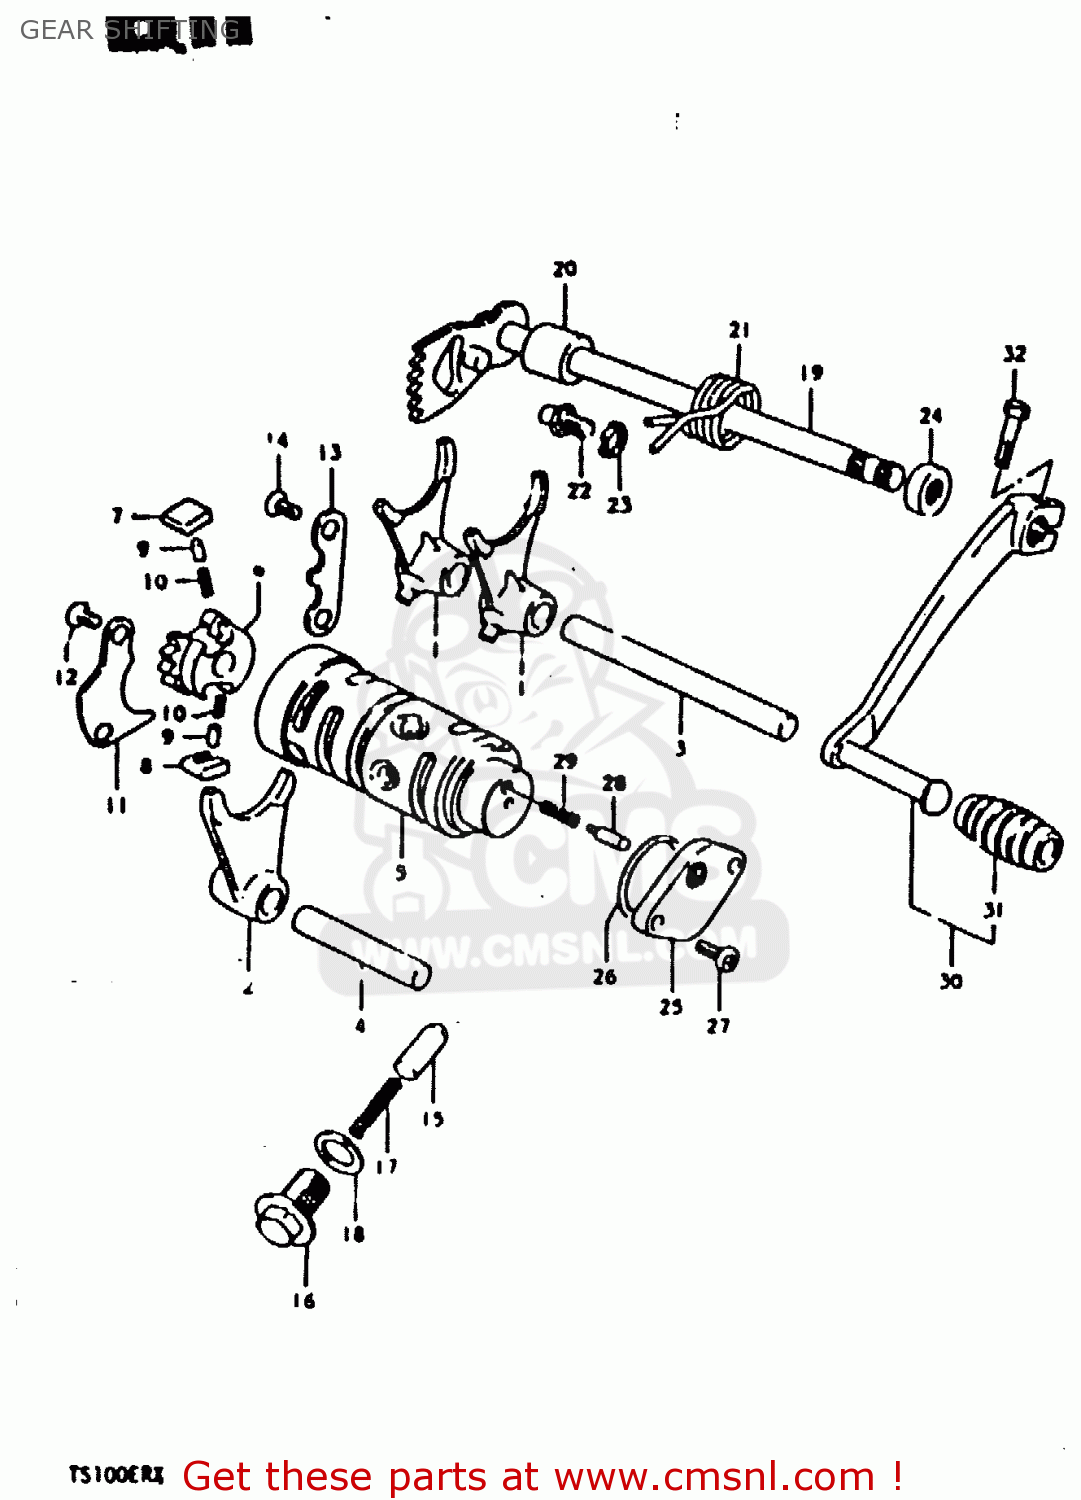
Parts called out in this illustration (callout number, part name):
1	FORK,GEAR SHIFT NO.1
2	FORK,GEAR SHIFT NO.2
3	SHAFT,GEAR SHIFT FORK
4	SHAFT,GEAR SHIFT FORK
5	CAM,GEAR SHIFT
6	RETAINER,GEAR SHIFT CAM
7	PAWL,GEAR SHIFT NO.1
8	PAWL,GEAR SHIFT NO.2
9	PIN(5X8)
10	SPRING
11	LIFTER,GEAR SHIFT PAWL
12	SCREW
13	GUIDE,GEAR SHIFTING CABLE
14	SCREW
15	STOPPER,GEAR SHIFTING
16	BOLT,GEAR SHAFT CAM STOPPER
17	SPRING
18	GASKET(14X19.2X2) (NAS)
19	SHAFT,GEAR SHIFT
20	SPACER(12X20X15.3)
21	SPRING
22	STOPPER,GEAR SHIFT CAM
23	WASHER
24	OIL SEAL
25	BODY,GEAR SHIFT SWITCH
26	O-RING (D:2.4 ID:26.2)
27	SCREW
28	PIN(5X15.5)
29	SPRING
30	LEVER ASSY,GEAR SHIFT
31	RUBBER,GEAR SHIFT PEDAL
32	BOLT
